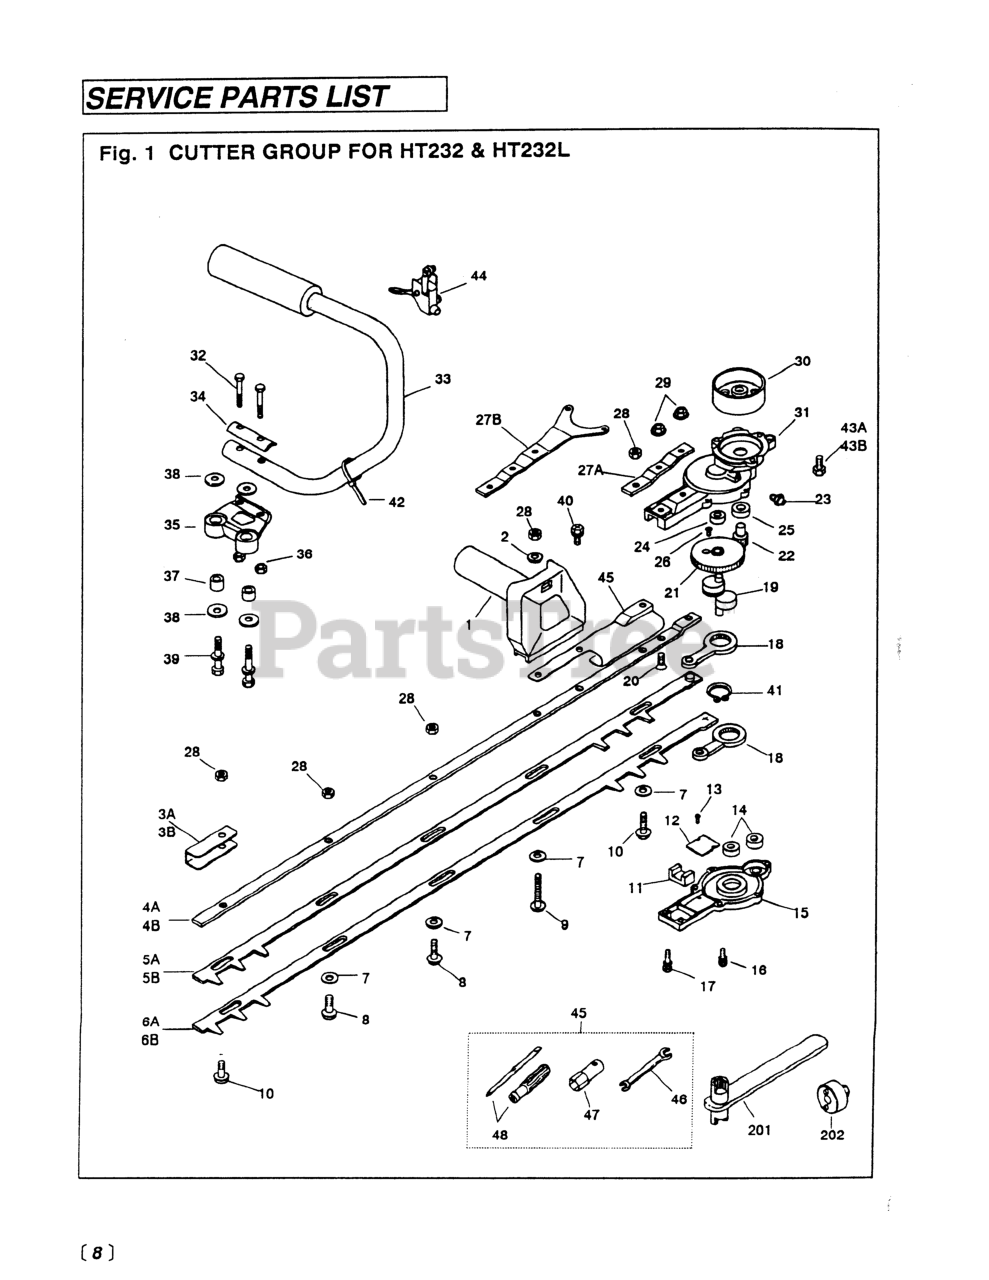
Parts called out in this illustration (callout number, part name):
1	HANDLE (RPLS -12100)
3A	REINFORCE, END
5A	BLADE, UPPER, 30
6A	BLADE, LOWER, 30
7	WASHER (RPLS 3873-11760)
11	FELT
12	PLATE
13	SCREW, M3 x 5
14	BEARING
15	CASE, LOWER
16	BOLT, M5 x 16
17	BOLT, M5 X 20
18	ROD
19	CRANKSHAFT
20	SCREW
21	GEAR
22	PINION
23	FITTING, GREASE
24	BEARING
25	BEARING
26	SCREW
27A	PLATE (RPLS 3880-11130)
28	NUT, M6
29	NUT
30	DRUM, CLUTCH
35	BRACKET
36	NUT (RPLS 3873-14470)
40	BOLT
41	RING, SNAP, M25 X 1.2
42	BAND, CABLE
43A	BOLT, M6 X 14
44	LEVER ASSEMBLY
45	PROTECTOR
46	SPANNER, 8 X 10 (RPLS 2540- )
47	SOCKET, HEX, 3/4
48	SCREWDRIVER
202	WRENCH (TOOL)
NI	TOOL SET
